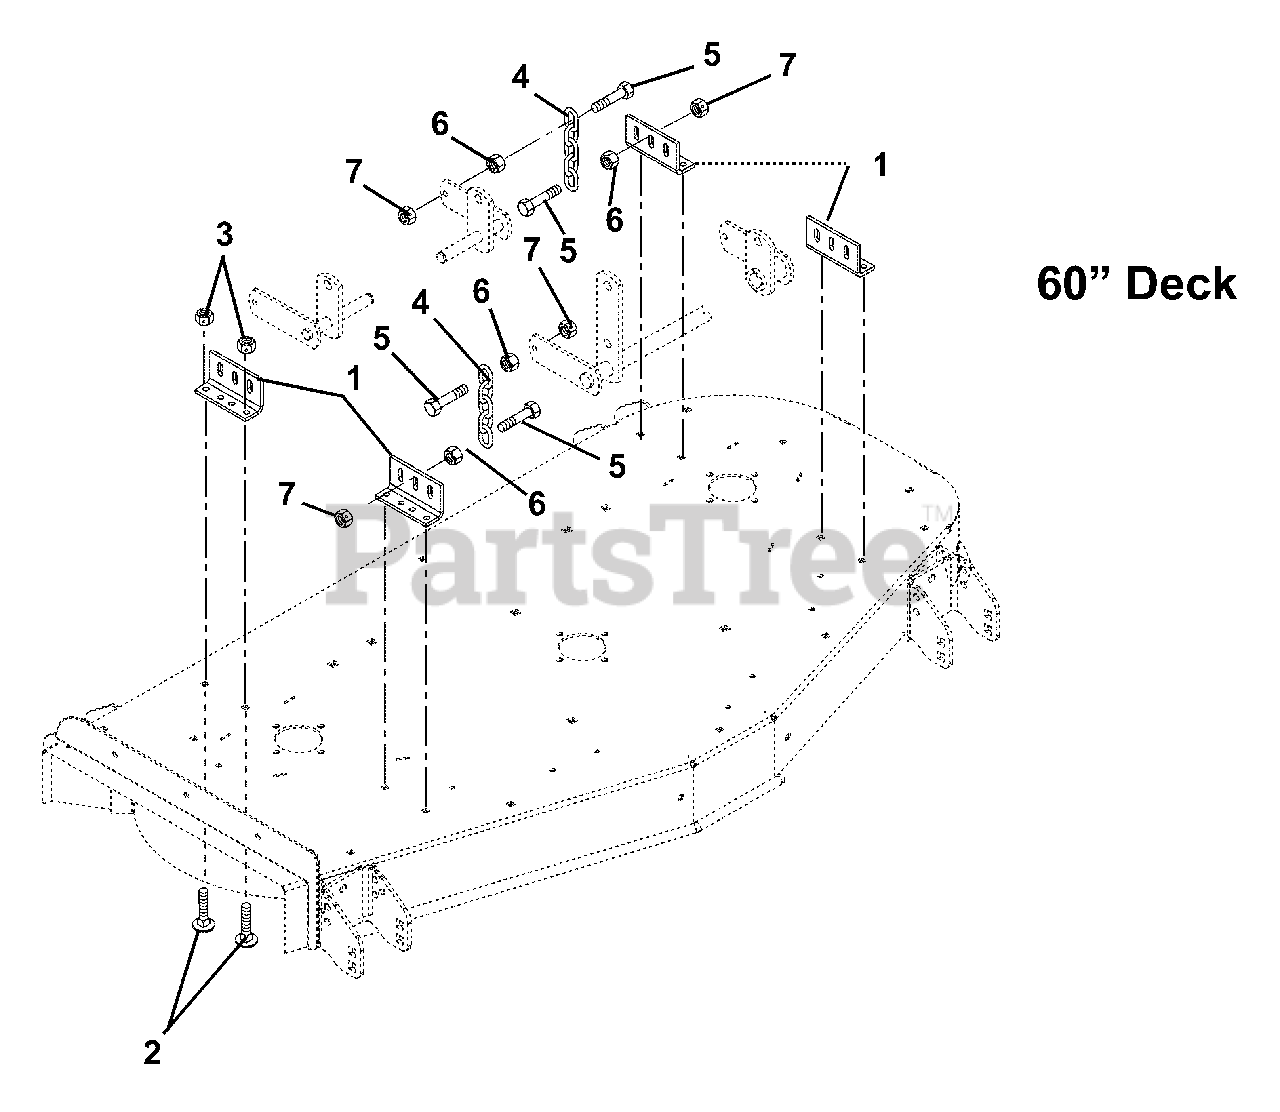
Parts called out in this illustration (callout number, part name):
1	MOWER MOUNTING BRACKET - RED
2	@BLT-RDHDSQNK .38-16X1.00 G5YZ
3	@NUT-LK-TOP-FLG .38-16 YWZC
4	CHAIN, LINK
5	BLT-HEX M12X1.75X55 GR5 YZ
6	NUT-SPNLK-FLG M12-1.75 YZ
7	NUT-LK-TOP-FLG M12-1.75 YZ
